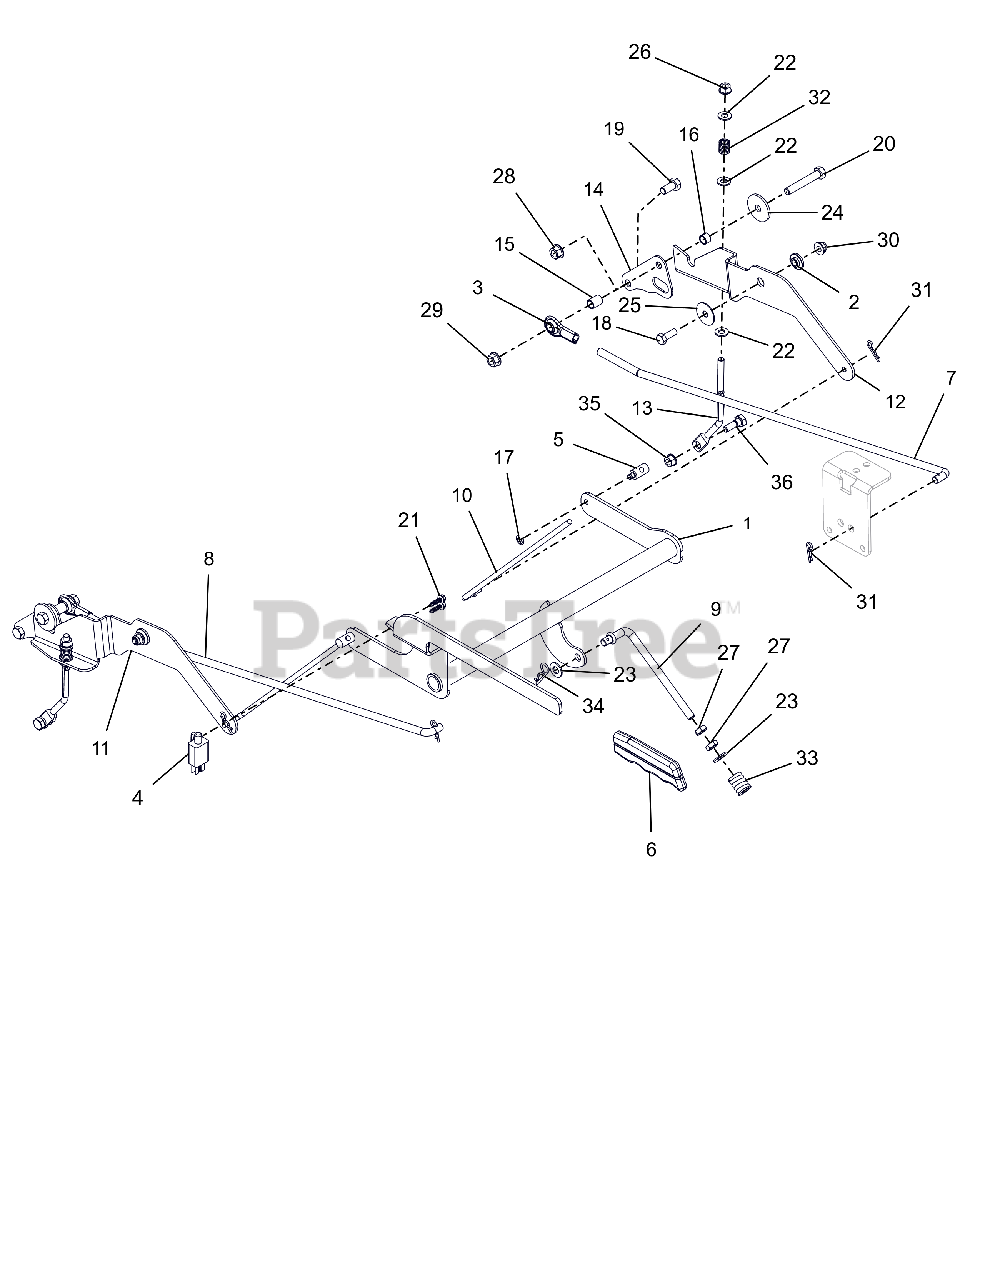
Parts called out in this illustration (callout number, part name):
1	WLDMT, BRAKE LEVER
2	BSHG, FLG .325X.499X.26X.88
3	ROD END, .38 RH
4	SWITCH- DOUBLE POLE N.O./N.O.
5	TRUNION, 1/4-20
6	GRIP, PARKING BRAKE (YELLOW)
7	STEERING, LINKAGE LH
8	STEERING, LINKAGE RH
9	LINK, OVER CENTER, PARKING BRK
10	LINK, BRAKE ARM
11	INTERLOCK, RH BRAKE LINK
12	INTERLOCK, LH BRAKE LINK
13	LINK, BRAKE (XL)
14	PLATE, TRANSAXLE ADAPTOR
15	SPCR, SLV .385X.500X.652
16	SPCR, SLV .385X.500X.350
17	RG-RTNG-EXT .250X.025
18	BLT, HEX .31-18X.875 G5 ZCC
19	BLT,HEX .38-16X.75 G5 ZCC
20	BLT,HEX .38-16X2.25 G5 ZCC
21	SCR, PLASTITE #12X.75 ZCC
22	WSHR,FLT .344X.688X.065 ZCC
23	WSHR,FLT .406X.812X.065 ZCC
24	WSHR, FLT .380X1.50X.125 ZCC
25	WSHR, FLT .347X1.254X.048 ZCC
26	NUT,LK-CTR-FLG .31-18 GF ZCC
27	NUT-JAM .375-16 G2 ZCC
28	NUT-LK-TOP-FLG .38-16 ZC120
29	NUT-LK-CTR-FLG .375-16 GF ZCC
30	NUT,LK-NYL-FLG .31-18 G5ZC120
31	PIN, HAIR #213 .08X1.19 ZCC
32	SPRING, COMPRESSION
33	SG-COMP .187X.56X1.62
34	PIN-HAIR CTR .09 X 1.50 YWZC
35	NUT-LK-TOP-FLG .312-18 GF ZCC
36	BOLT,SHLDR .38X.25 -.31-18X.75
